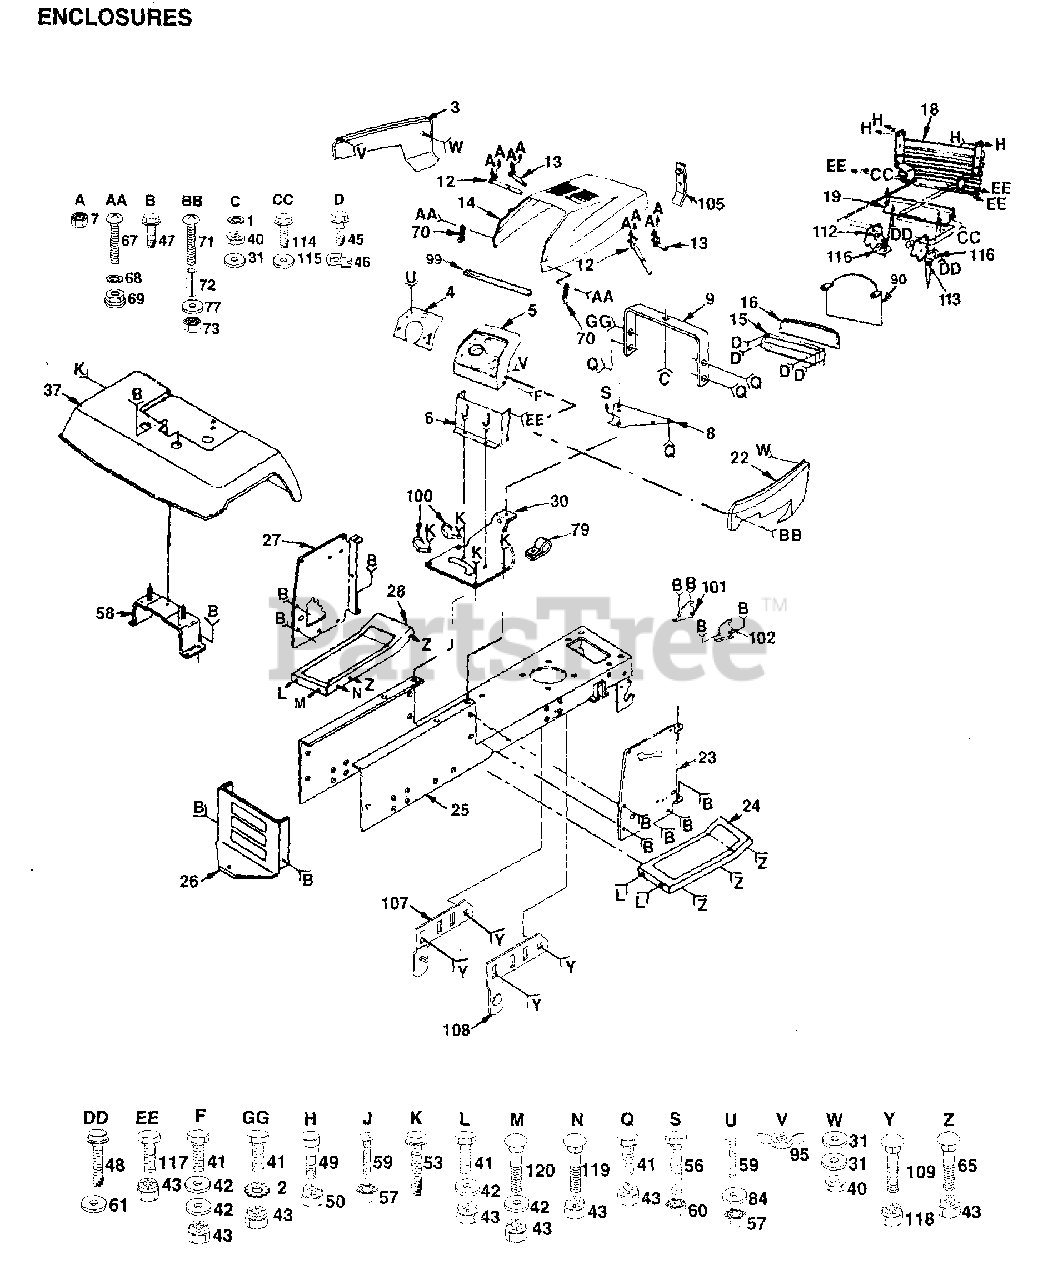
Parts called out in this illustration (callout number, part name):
1	LOCKWASHER
2	LOCKWASHER
3	"PANEL,SIDE LH "
7	NUT
9	SUPPORT ASS'Y
16	LENS LT
22	"PANEL,SIDE RH"
27	DASH PANEL LH
30	SADDLE. 6SP
31	WASHER PM
42	WASHER
46	"""J"" FASTENER LT"
47	SCREW
48	SCREW
53	SCREW LT
56	BOLT
58	BRKT FENDER
59	SCREW
61	WASHER
65	BOLT
67	SCREW
68	LOCKWASHER
69	WELDNUT
70	HOOD LATCH T
71	SCREW
72	SPACER LT
77	WASHER
79	CLIP T
84	WASHER
90	"BAFFLE,VERTICLE"
99	FOAM STRIP T
100	"CLIP,INSULATOR"
101	SUPPORT LH YTH
102	SUPPORT RH YTH
107	PIVOT BRKT LH
108	PIVOT BRKT RH
112	SUPPORT LH YTH
113	SUPPORT RH YTH
114	SCREW HEX CRT
115	WASHER
116	WASHER
117	BOLT
118	NUT
